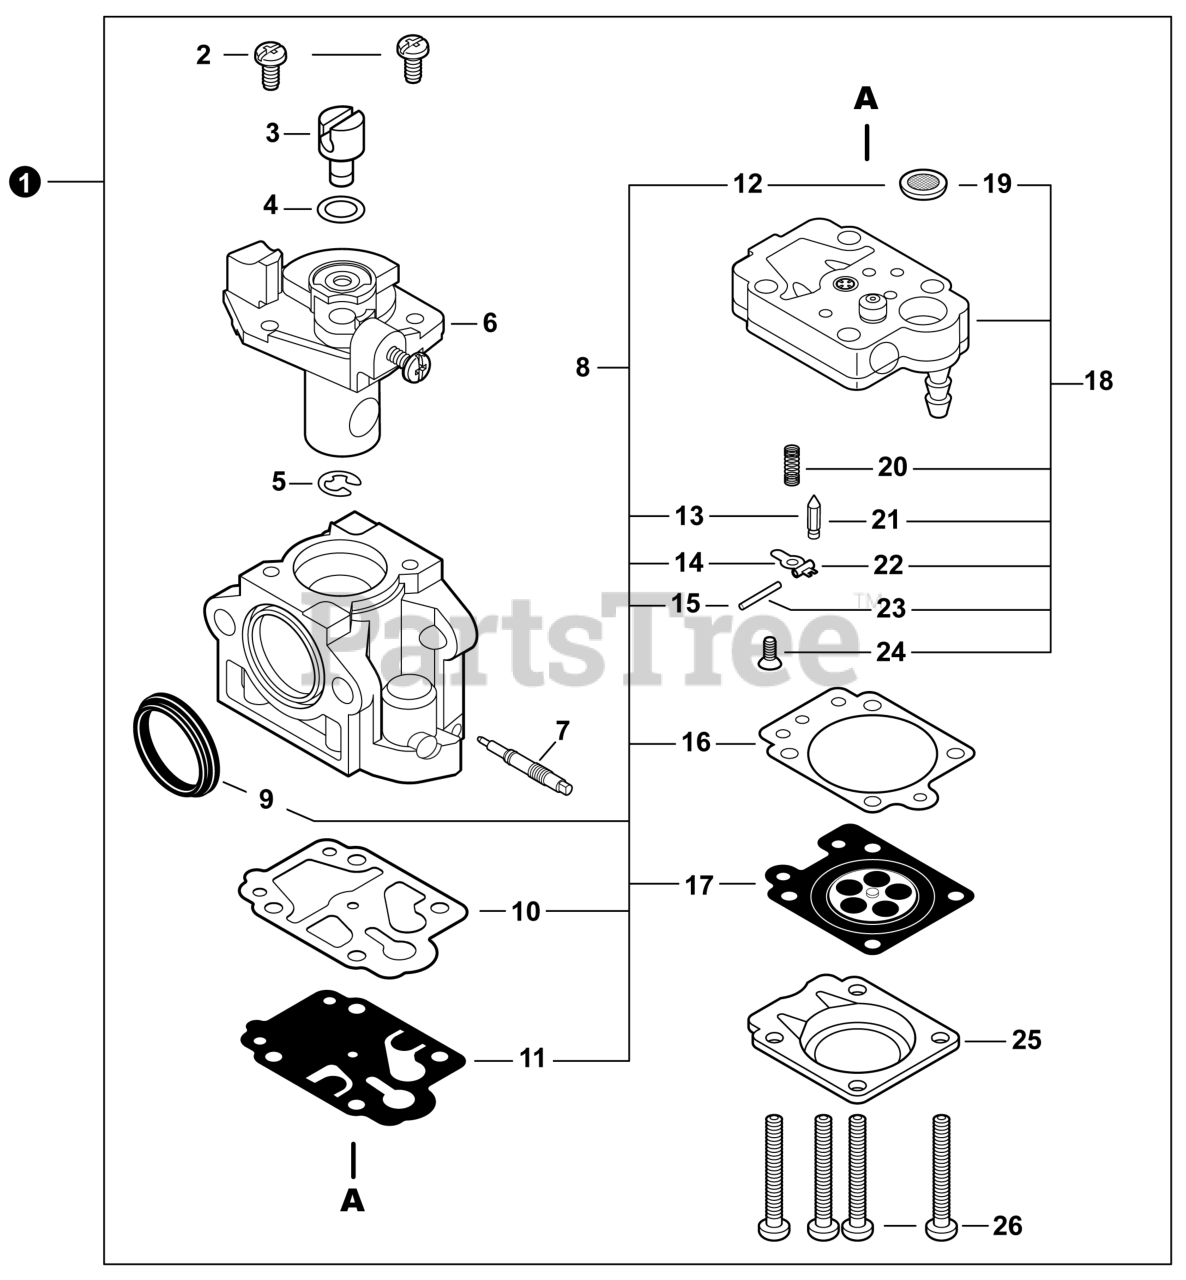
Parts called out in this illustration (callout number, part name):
1	CARBURETOR - WYK-387
6	VALVE, THROTTLE
7	NEEDLE, HIGH SPEED
8	REPAIR KIT, CARBURETOR
9	RING, PACKING
10	GASKET, PUMP
11	DIAPHRAGM, FUEL PUMP
12	SCREEN, FUEL INLET
13	VALVE, INLET NEEDLE
14	LEVER, METERING
15	PIN, METERING LEVER
16	GASKET, METERING DIAPHRAGM
17	DIAPHRAGM, METERING
18	BODY ASSY, PUMP
19	SCREEN, FUEL INLET
20	SPRING, METERING LEVER
21	VALVE, INLET NEEDLE
22	LEVER, METERING
23	PIN, METERING LEVER
24	SCREW
25	COVER, METERING DIAPHRAGM
